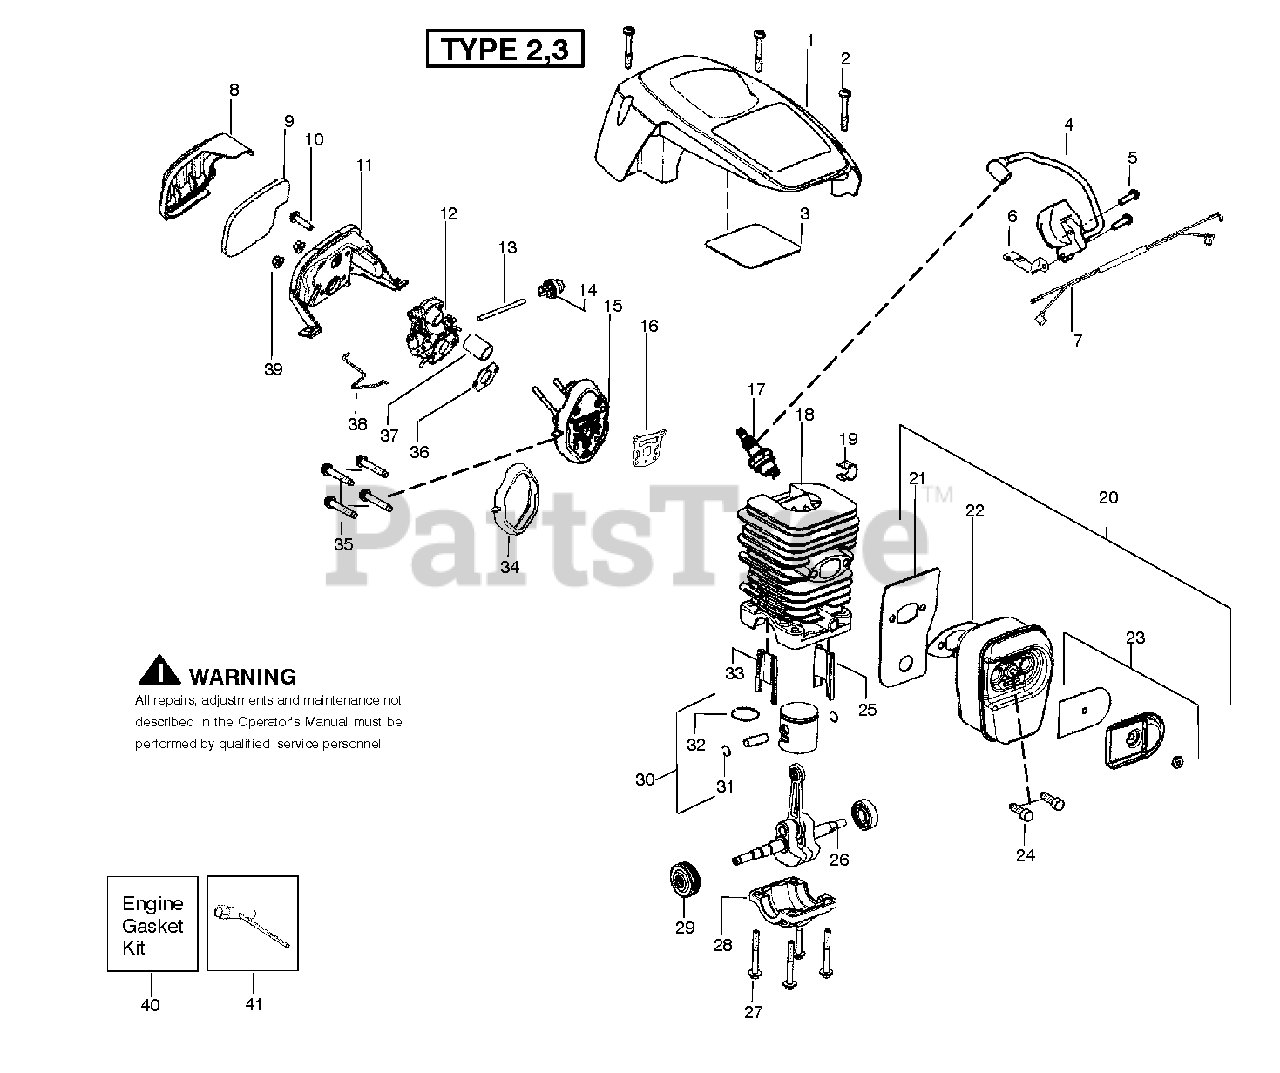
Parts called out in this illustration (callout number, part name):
1	SHIELD
3	TAPE REFLECTOR
5	SCREW M5.38-14X22.225MM
6	GROUND STRAP
7	ASSY WIRE HARNESS
8	COVER, AIR FILTER
9	FILTER AIR
10	SCREW M5-0.8X16
11	HSG FILTER
12	Poulan TBD
12	CARB ZAMA W26B W/PURGE
13	KIT-LINE
14	AIR PURGE
15	KIT CARB ADAPTOR
16	KIT GASKET SAS
17	SPARK PLUG (RCJ-7Y)
18	KIT CYLINDER
19	CLIP-HIGH TENSION LEAD
20	KIT MUFFLER SAS NON CAT
21	PLATE BACK MUFFLER
22	KIT GASKET SAS
23	KIT SPARK ARRESTOR SAS NCAT
24	SCREW MUFFLER
25	INSERT TRANSFER LEFT
26	CRANKSHAFT & ROD ASSY
27	BOLT M6-1.0 X 25MM
28	HUB CAP CRANKCASE
29	BEARING & SEAL ASSEMBLY
30	KIT PISTON
31	C-CLIP,PSTN PIN 36/41
32	RING-PISTON
33	INSERT TRANSFER RIGHT
34	KIT GASKET SAS
35	SCREW M5-0.8X30MM
36	KIT GASKET SAS
37	TUBE INTAKE
38	WIRE THROTTLE
40	KIT GASKET SAS
41	WRENCH-BAR
